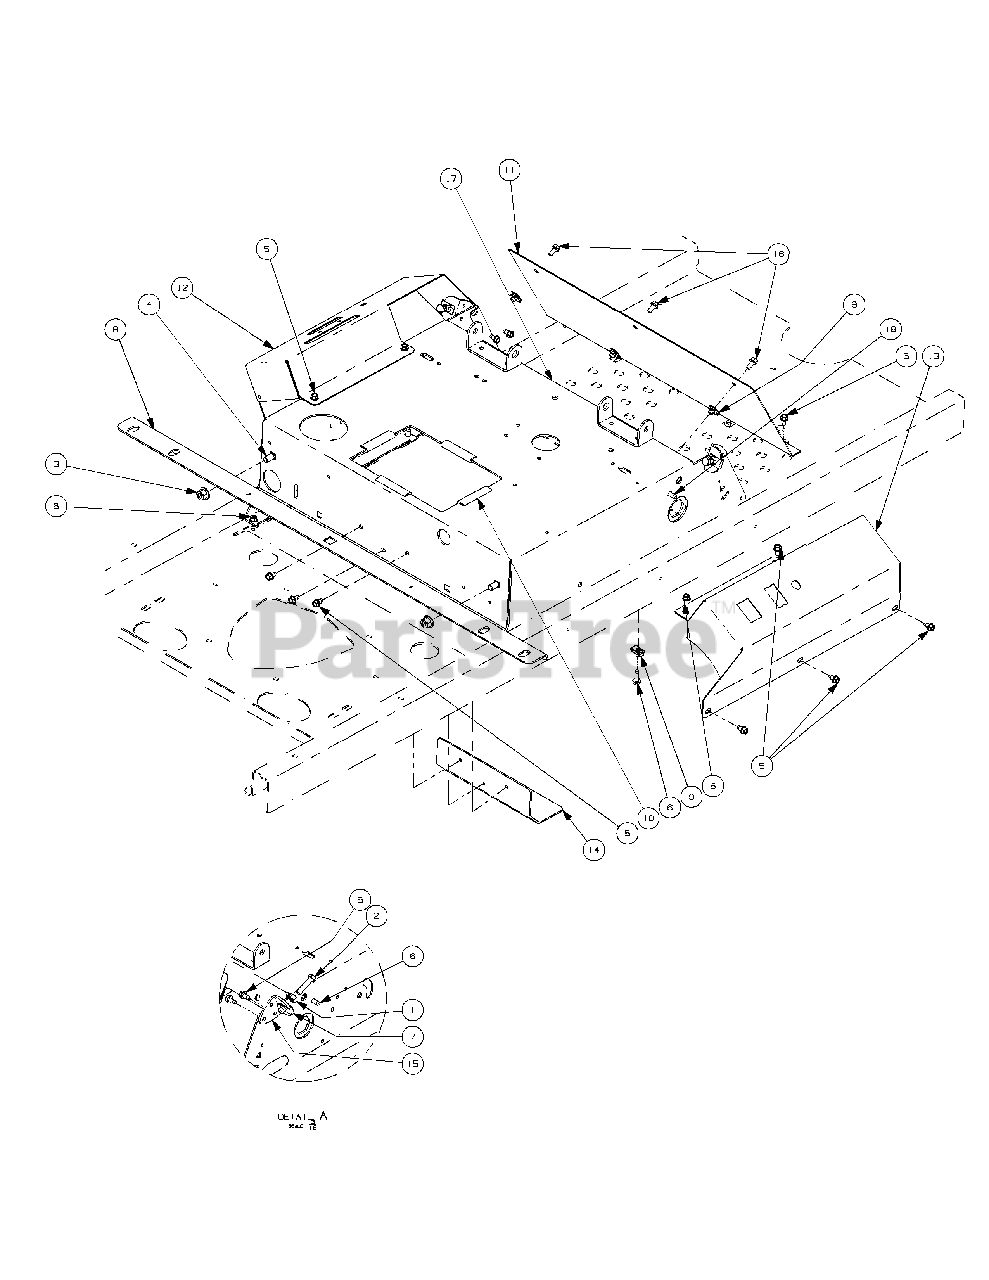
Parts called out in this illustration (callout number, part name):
1	Hex Nut, 5/16-18
2	HHCS, 5/16-18 x 1-1/4
3	Hex Nut, 3/8-16 Flange Lock
4	Carriage Bolt, 3/8-16
5	Screw, 1/4-20 x 1/2
6	Self Tapping Screw, 1/4-20 x .75
7	U-Nut, 5/16-18
8	Front Tank Mounting Bracket
9	U-Nut, 1/4-20
10	Battery Edge Trim
11	Front Panel
12	Left Hand Control Console
13	Right Hand Control Console
14	Battery Bracket
15	Forward/Reverse Stop Bracket
16	Screw, 1/4-20 x 1/2
17	Control Housing Weldment
18	Self Tapping Screw 5/16-18 x .750
